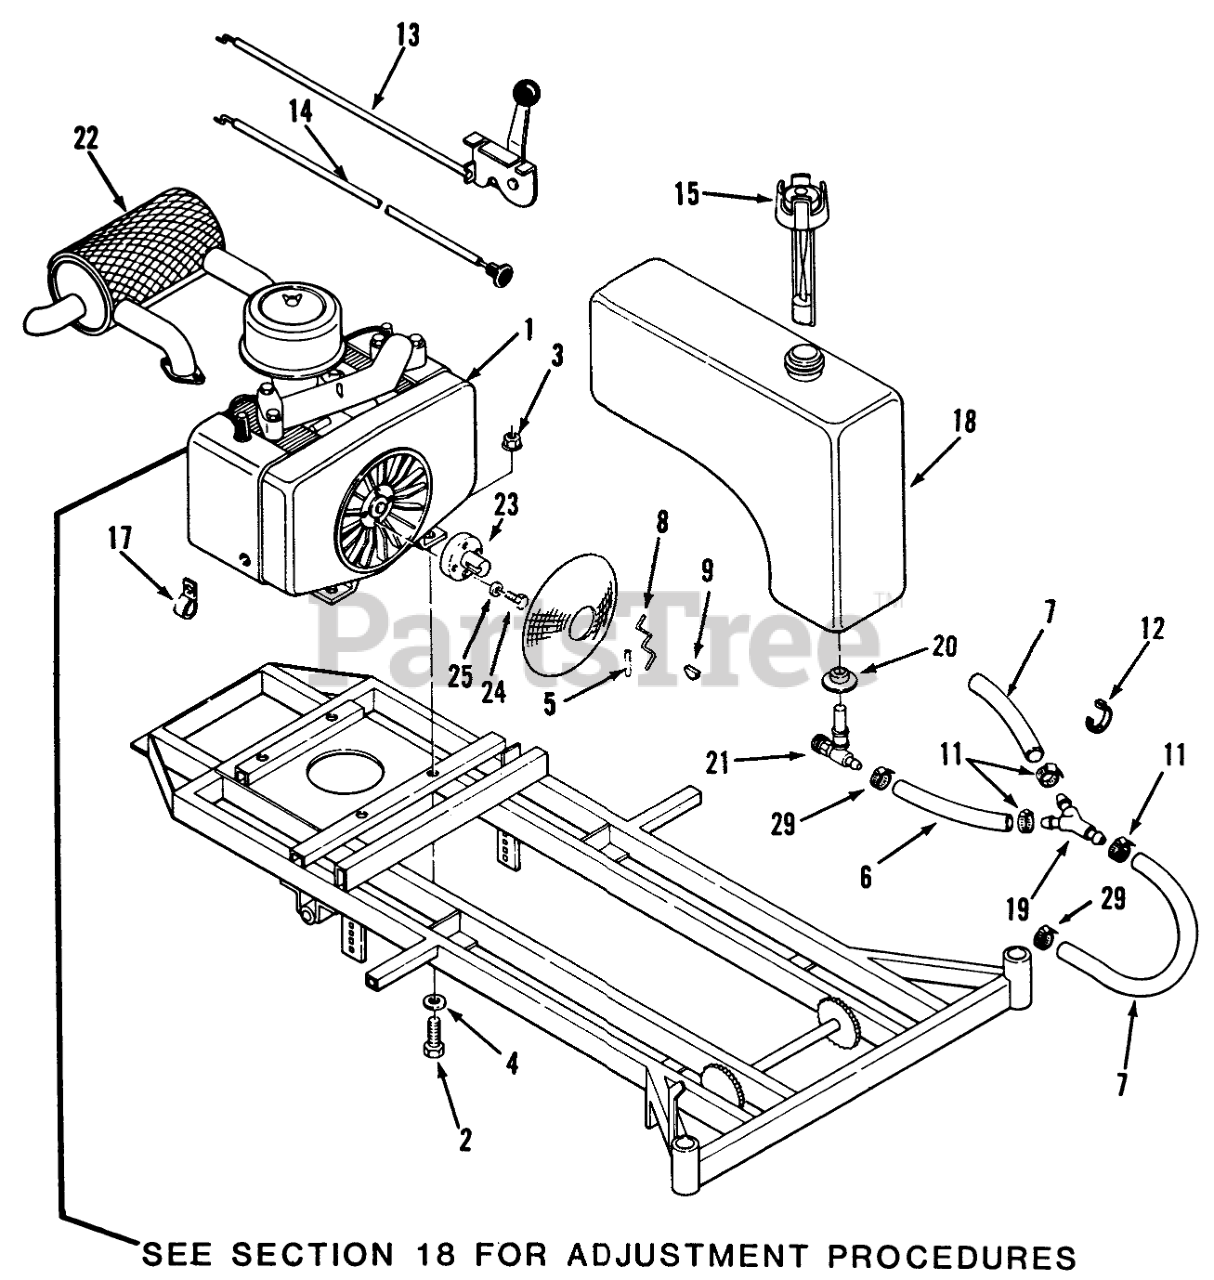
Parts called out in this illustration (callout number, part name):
1	Engine-18 HP Kohler (M18S Spec. No. 24529)
3	NUT
8	Lock Wire
9	KEY-WOODRUFF
17	CLIP
21	VALVE-FUEL
